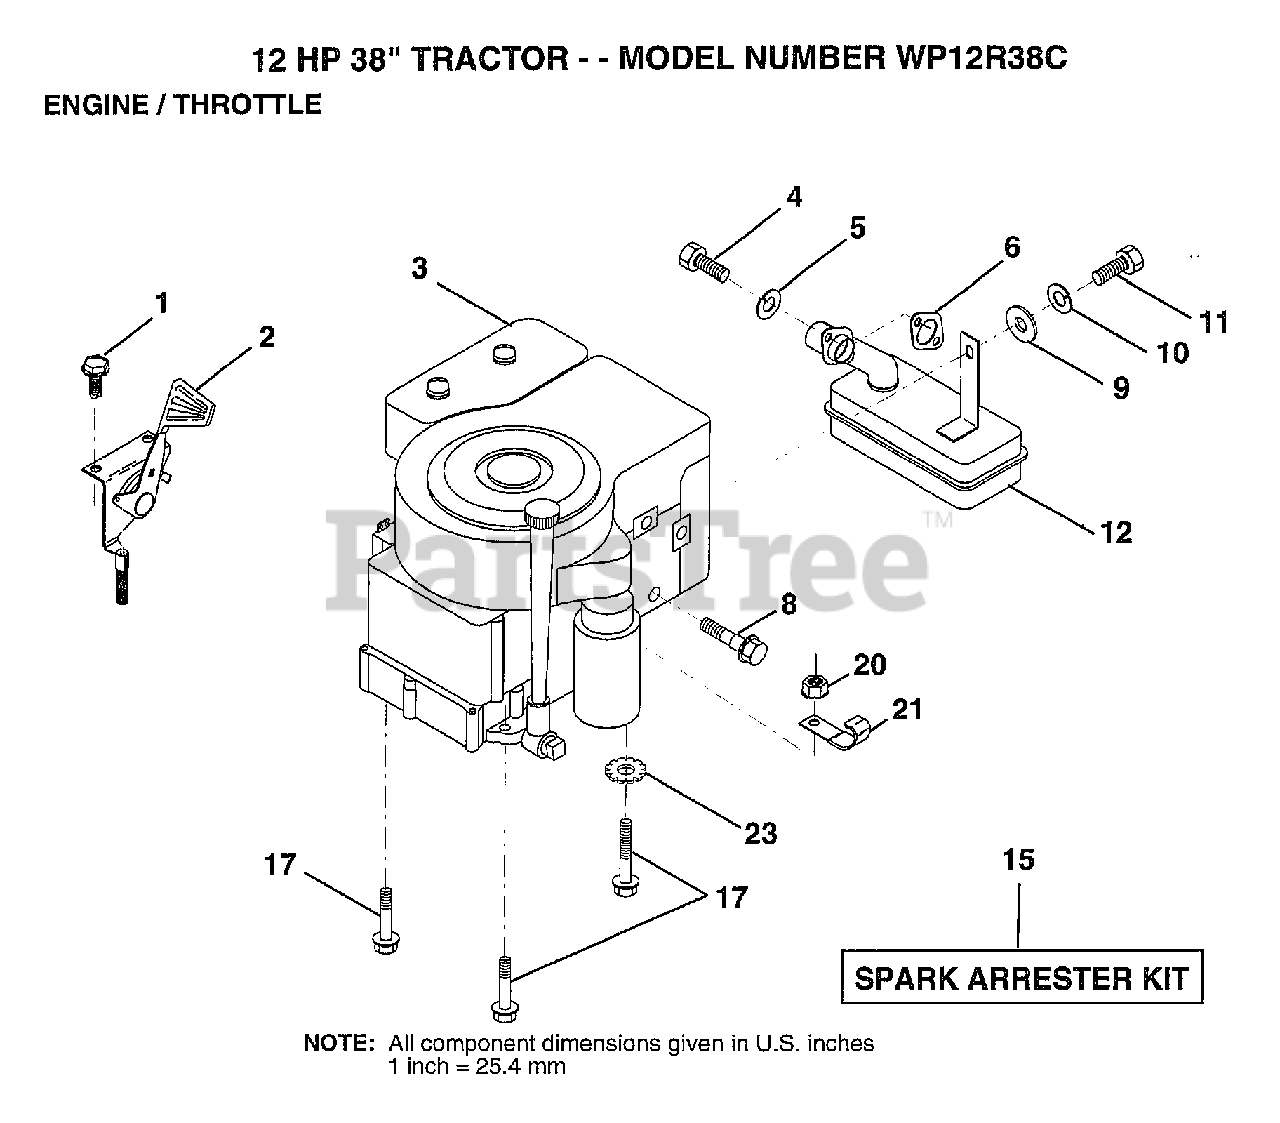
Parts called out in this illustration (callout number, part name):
1	SCREW.1/4-20X1/2
2	"CONTROL,THROTTLE"
4	SCREW
5	LOCKWASHER
8	BOLT T
10	LOCKWASHER
12	MUFFLER
17	SCREW LT
20	NUT
21	CLIP T
23	LOCKWASHER
